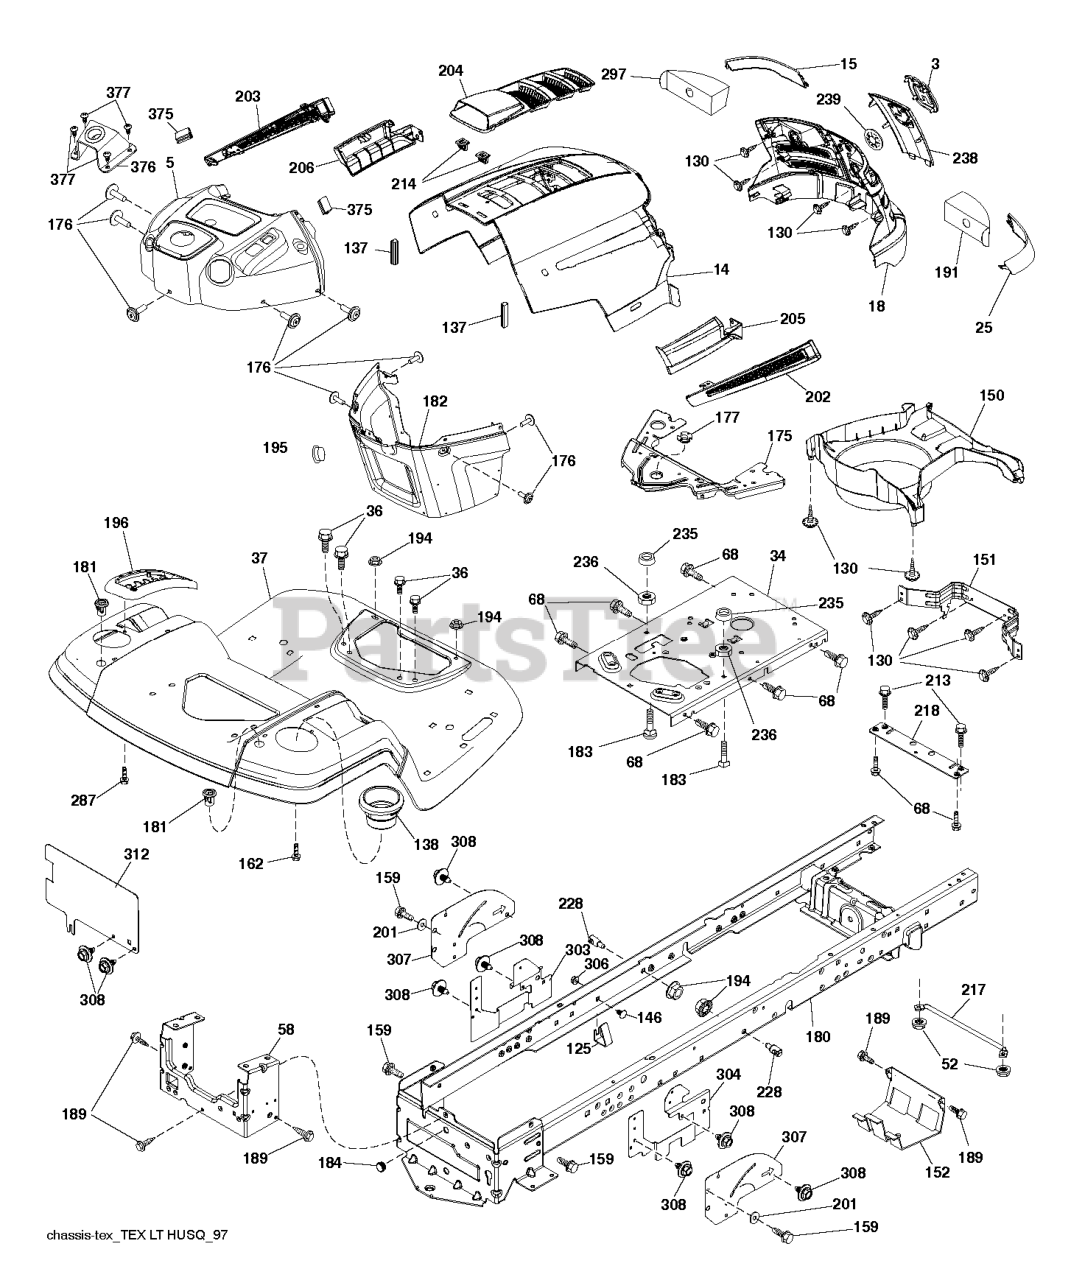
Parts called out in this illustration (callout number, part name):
3	LOGO.HUSQ.GT.LT.CROWN.H
5	SUBASM.DASH.UPPER.W/BUMPER
5	DASH.UP.HU.LT.CBL.CLTCH.CHG.PT
5	DASH.UPPER.HUS.LT.CABLE.CLUTCH
14	HOOD.HUSQVARNA.LT.ORANGE
15	LENS.HUSQVARNA LT.RH
18	ASM.GRILLE HUSQVARNA.LT.498
18	GRILLE.SVC.HUSQVARNA.L
25	LENS.HUSQVARNA LT.RH
34	PLATE.ENGINE.WELDED.CHASSIS
36	SCREW 5/16"
37	FENDER.TLT.PDL.CNTRL.W/CPH.ORG
58	DRAWBAR UPPER 2PC SMALL FENDER
125	CLIP.FUEL.LINE
130	SCREW.#10 X 0.750.BOS
137	BUMPER DASH
138	HOLDER.CUP.LT.GREY
146	BOLT.RDHD.SHT.SQNK.3/8-16X5/8
151	BRACKET PIVOT
152	SHIELD.BROWNING.W/TEX
159	SCREW, 3/8-16X3/4
162	SCREW.HI-LO.CONSOLE
175	CROSSMEMBER
176	SCREW.#10-24X5/8.RN.QU
177	BUSHING STEERING
180	CHASS.WLDMNT.TL.12GA/2P.48/54
181	BUSHING.MNT.FEND.CRGO.TEX.49
182	DASH.LOWER.PREDATOR LT
183	BOLT.5/16-18X1-1/4 FULL THD
184	PLUG.DEMO.625
189	SCREW
191	INSERT.REFLECTIVE.RH.
194	NUT HEX,LOCK,FLAN
195	PLUG.TEX.DASH.SVC.MINDER.GREY
196	DECKLFT.CONSOL FULL ASSM GREY
201	WASHER
202	VENT.SIDE.HUSQVARNA.LT.RT
203	VENT.SIDE.HUSQVARNA.LT.LFT
204	SUBASM.TOP.VENT.HUSQ.LT
205	SKIRT.SIDE.HUSQVARNA.LT.RT
206	SKIRT.SIDE.HUSQVARNA.LT.LEFT
213	SCREW HEXAGON HEAD SCREW 5/16-
213	HCS 5/16C X 3/4
214	CLIP.RETAINER.TINNER.
217	ROD.PIVOT.HOOD
218	X-PIECE.HOOD.STOP.NON/
228	STUD.W/"D"ANTI-ROTATION
228	STUD.FASTNER.W/ANTI-ROTATE
235	Spacers
235	SPACER FENDER
236	NUT.CENTERLOCK.5/16-
238	TRIM.HUSQ LT.668
287	SCREW 1/4X20
297	INSERT REFLECTIVE
303	SHIELD.LOWER.LH/LT/GT/BLK.EDIP
303	SHIELD.LWR.LH.LTGT.NON30
304	SHIELD.LWR.RH.LTGT.NON30.NOTCH
304	SHIELD.RH.LOW.LT/GT.NON-30.PNT
306	NUT LOCK FLG 3/8-16 UNC
307	SHIELD.UPPER.LT.GT.ISO
308	BOLT.5/16-18UNCX3/4 W/SEMS.BLK
312	COVER DRBAR.LT.FRTTANK.ISO X43
375	BUMPER CLIP-ON. DASH 1"
376	MOUNT.ASM.HUSLT.UPPER.STRNG
377	SCREW 10 X 1/2 ZN PL PHIL PAN
